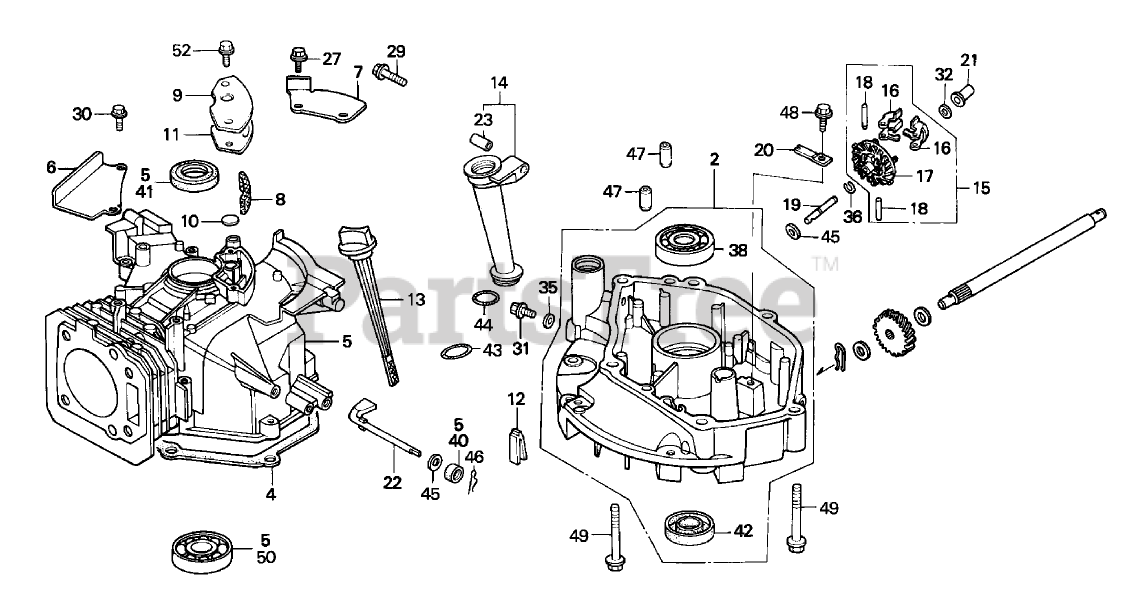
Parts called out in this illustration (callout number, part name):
2	Oil Pan Assembly
4	GASKET-PAN, OIL
5	CYLINDER ASM
6	Plate-Guide
7	Plate A-Guide
8	Filter-Breather
9	Cover-Breather
10	VALVE-BREATHER
11	GASKET-COVER, BREATHER
12	Rubber-Oil, Return
13	Dipstick-Oil
14	EXTENSION-FILLER, OIL (106 mm)
15	GOVERNOR ASM
16	Weight-Governor
17	HOLDER-WEIGHT, GOVERNOR
18	PIN-WEIGHT, GOVERNOR
19	SHAFT-HOLDER, GOVERNOR
20	Plate-HOLDER, Governor Shaft
21	SLIDER-GOVERNOR
22	SHAFT-ARM, GOVERNOR
23	Collar-Extension
27	BOLT-FLANGE (6X12) (C T200)
29	Bolt-Flange (6X32)
30	BOLT-FLANGE (6X20) (C T200) (engine serial numbers up to 6702082)
31	Bolt-PLUG, Drain
32	WASHER-THRUST (6MM)
35	WASHER-PLUG, DRAIN (102MM)
36	Clip-Governor Holder
40	SEAL-OIL (6X11X4)
41	SEAL-OIL (25X38X7)
42	SEAL-OIL (25.4X40X7)
43	O-Ring (22.5X2.2)
44	O-Ring (26X2.7)
45	WASHER-PLAIN (6MM)
46	PIN-LOCK (8MM)
47	Pin-Dowel (8X14)
48	Bolt-Flange (6X12)
49	BOLT-FLANGE (8X50)
50	BEARING-BALL, RADIAL (6205)
52	BOLT-FLANGE (6X14) (C T200)
